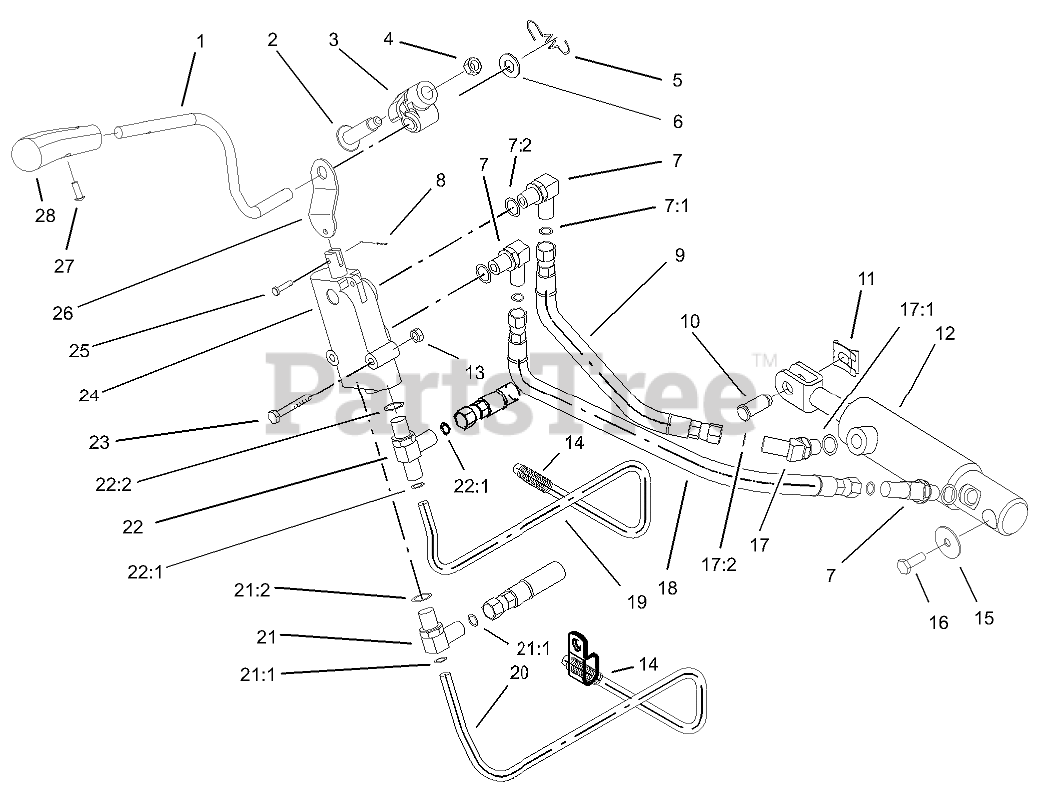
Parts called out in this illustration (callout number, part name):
1	HANDLE-LIFT
2	BOLT-SHOULDER
3	TRUNNION-LEVER, LIFT
4	NUT-JAM, LOCKING
5	SPRING-EXTENSION, LIFT
6	WASHER
7	FITTING-HYD, 90 DEGREE
7:1	O-RING
7:2	O-RING
8	PIN-COTTER
9	HOSE ASM
10	PIN-CLEVIS
11	CLIP-PIN
12	LIFT CYLINDER ASM
13	NUT-LOCK, NI
14	COVER-BRACE
15	WASHER-FLAT
16	SCREW-THREAD LOCKING
17	FITTING-HYD, 45 DEGREE
17:1	O-RING
17:2	O-RING
18	HOSE ASM
19	TUBE-HYD
20	TUBE - HYDRAULIC
21	FITTING-HYD. STRAIGHT
21:1	O-RING
21:2	O-RING
22	FITTING-HYD, LONG
22:1	O-RING
22:2	O-RING
23	SCREW-HH
24	VALVE - HYDRO LIFT
25	PIN-CLEVIS
26	LINK-LIFT
27	SCREW-PPHTF
28	KNOB-LIFT
